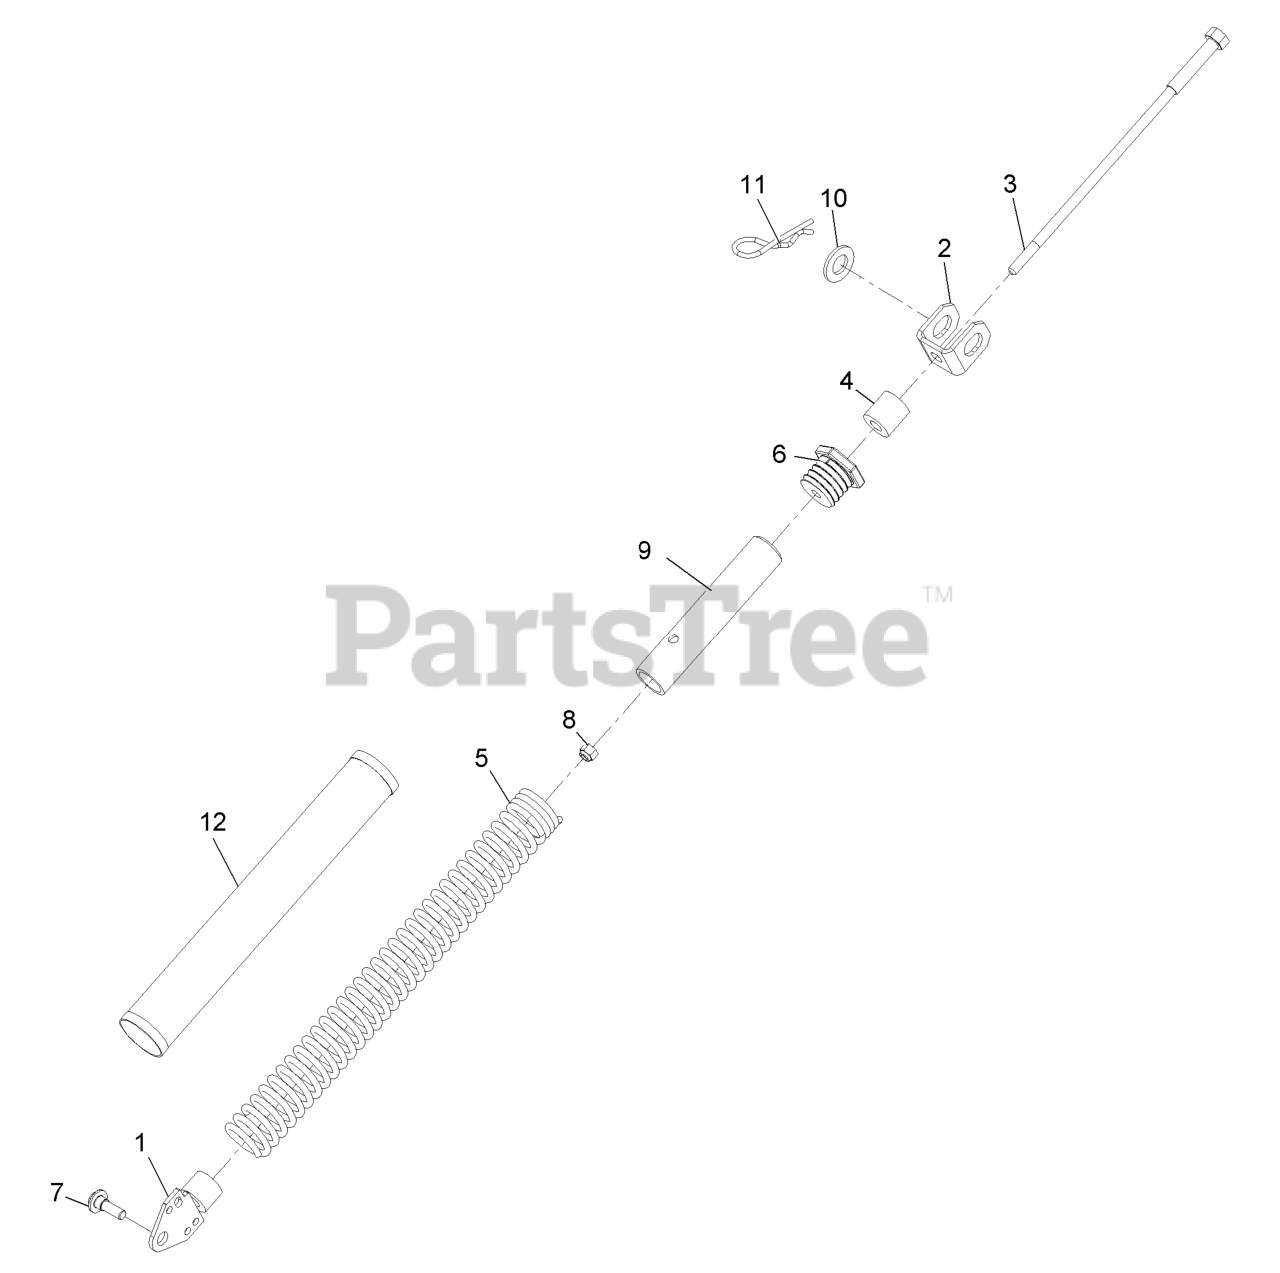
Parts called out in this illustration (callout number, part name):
1	TENSIONER-SPRING
2	MOUNT-LIFT ASSIST, DECK
3	SHAFT-ADJUSTMENT, SPRING
4	SPACER (PLATED)
5	SPRING-EXTENSION
6	PLUG-ADJUSTER, SPRING
7	SCREW-SHOULDER, HWH
8	NUT-LOCK, NI
9	SPRING-TUBE
10	WASHER-FLAT
11	PIN-CUT HEIGHT
12	COVER-SPRING, DECK
